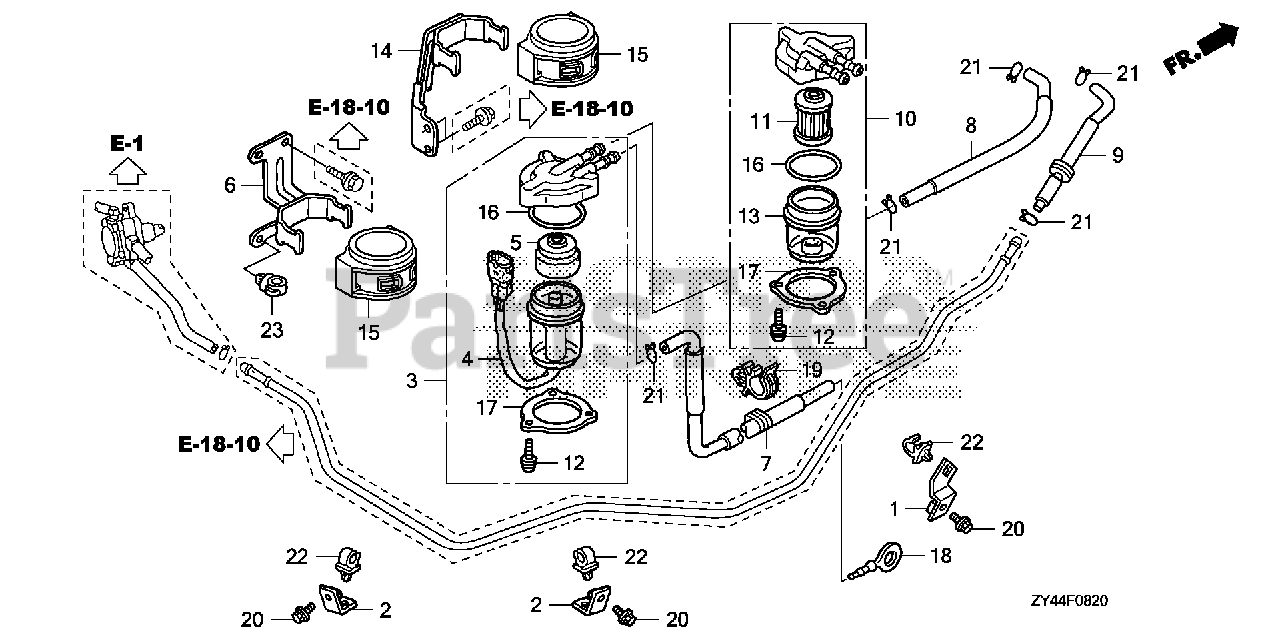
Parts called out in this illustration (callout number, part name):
1	STAY, FUEL PIPE A
2	STAY, FUEL PIPE B
3	SEPARATOR ASSY., WATER
4	CUP, WATER SEPARATOR
5	BUFFER, PLATE
6	STAY, WATER SEPARATOR
7	TUBE, FUEL (A)
8	TUBE, FUEL (B)
9	TUBE, FUEL (C)
10	FILTER, FUEL
11	FILTER, FUEL
12	SCREW, PAN (5X12)
13	CUP, FUEL STRAINER
14	STAY, FUEL STRAINER
15	SUSPENSION, STRAINER
18	PLUG, FUEL TUBE
19	HOLDER, ROD (A)
20	BOLT, FLANGE (6X12)
21	CLIP, TUBE (B12)
22	CLAMP, WIRE (8MM)
23	CLIP, WIRE HARNESS (25MM)
